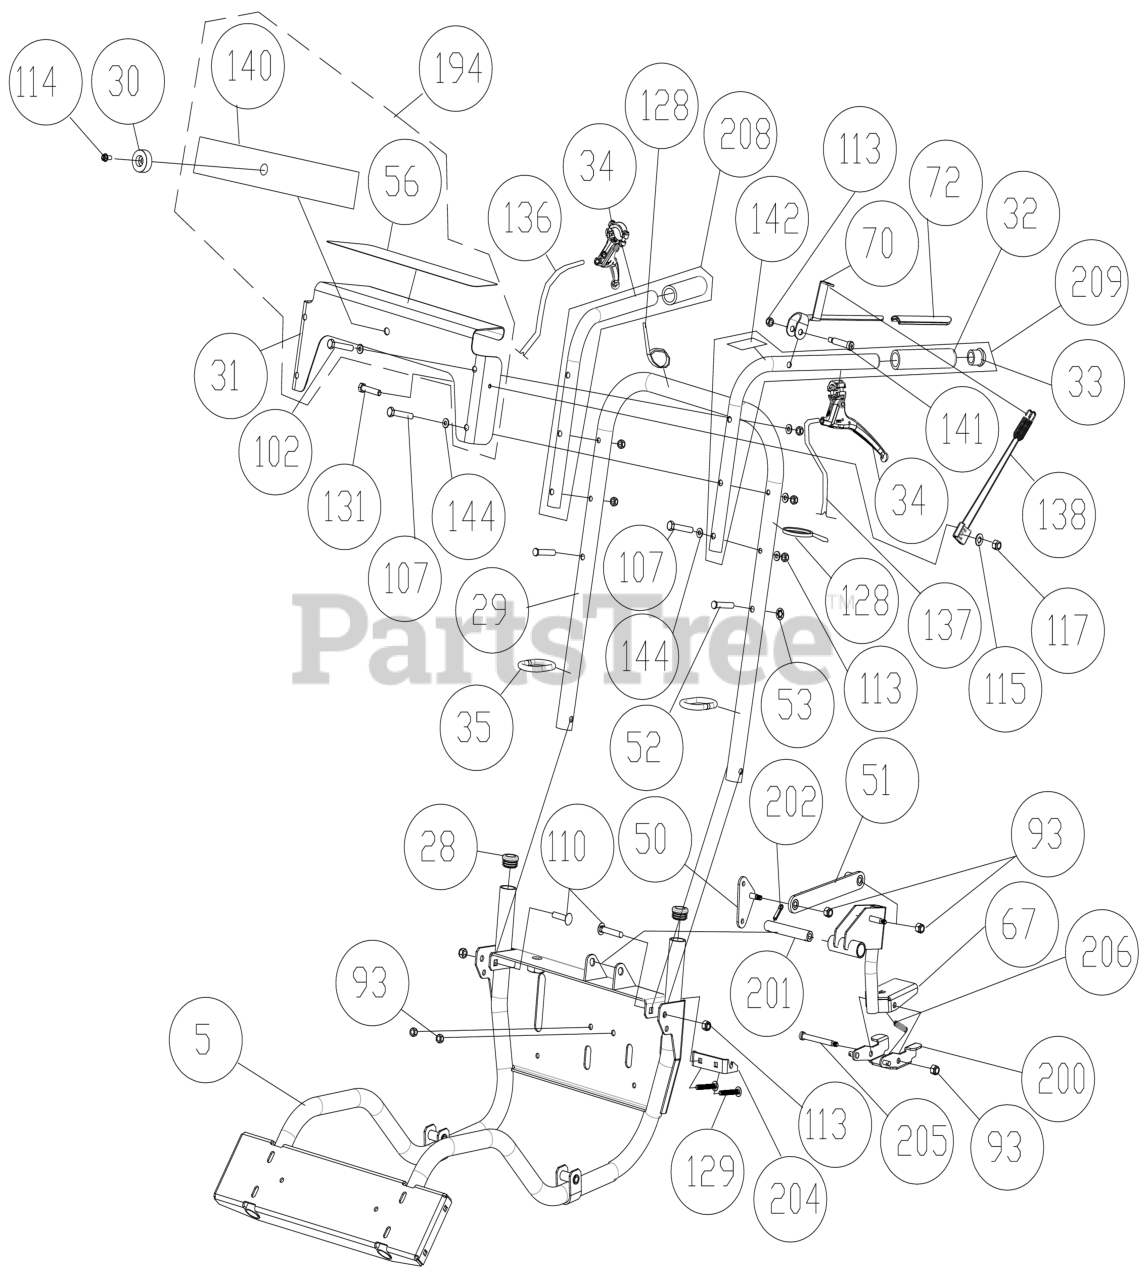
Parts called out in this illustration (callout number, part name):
5	FRAME SUPPORT OS900SP WA
28	PLUG TUBE INSERT 1.25" O.D.
29	HANDLE FOLDING
30	BUMPER RECESS
31	BRACKET CONSOLE
32	GRIP HANDLE
33	PLUG TUBE INSERT 1" OD
34	CONTROL MAGURA
35	LOOP FOLDING HANDLE
50	ENGINE BRACKET WA OS901SP
51	LINKAGE, FOOT CONTROL WA OS901SP
52	PIN CLEVIS 3/8 X 2.125
53	RETAINER 3/8" BOLT PUSH NUT
56	LABEL INSTRUCTION
67	PEDAL ASSY (PLUG/TREAD/BUSHINGS) OS901SP
70	SEE: 351624
72	GRIP LEVER 0.125" X 1" X 5" ORANGE
93	NUT LOCK 5/16"-18 HEX Z/P
102	SCREWCAP 3/8"-16 X 1 3/4" HCS ZP
107	SCREWCAP 3/8"-16X3" HCS ZP
110	BOLT CARRIAGE 3/8"-16 X 2" ZP
113	NUT LOCK 3/8"-16 HEX
114	SCREW SELF TAP 1/4"-20 X 5/8" HWH TYPE F
115	WASHER 1/4"SAE9/32"X5/8"X1/16"
117	NUT LOCK 1/4"-20 HEX Z/P
129	BOLT CARRIAGE 5/16"-18 X 3/4" ZP
131	SCREWCAP 1/4"-20 X 1" HCS ZP
136	CABLE SPEED CONTROL RT
137	CABLE SPEED CONTROL LFT
138	CABLE CLUTCH SEEDING CONTROL
141	BOLT SHOULDER 3/8" X 1 1/4"
142	LABEL CLUTCH BLADE
144	WASHER 3/8"FC7/16"X1"X5/64"
200	RELEASE PEDAL WA OS901SP
201	SHAFT, INNER PIVOT
202	PIN COTTER 1/8" X 1" Z/P
204	BRACKET, PIN CATCH
205	BOLT SHOULDER, 3/8" DIA. X 3.25" LONG
206	SPRING, RELEASE PEDAL
208	HANDLE W/GRIP RIGHT OSSP SERVICE
209	HANDLE W/GRIP LABELS LEFT OSSP SERVICE
